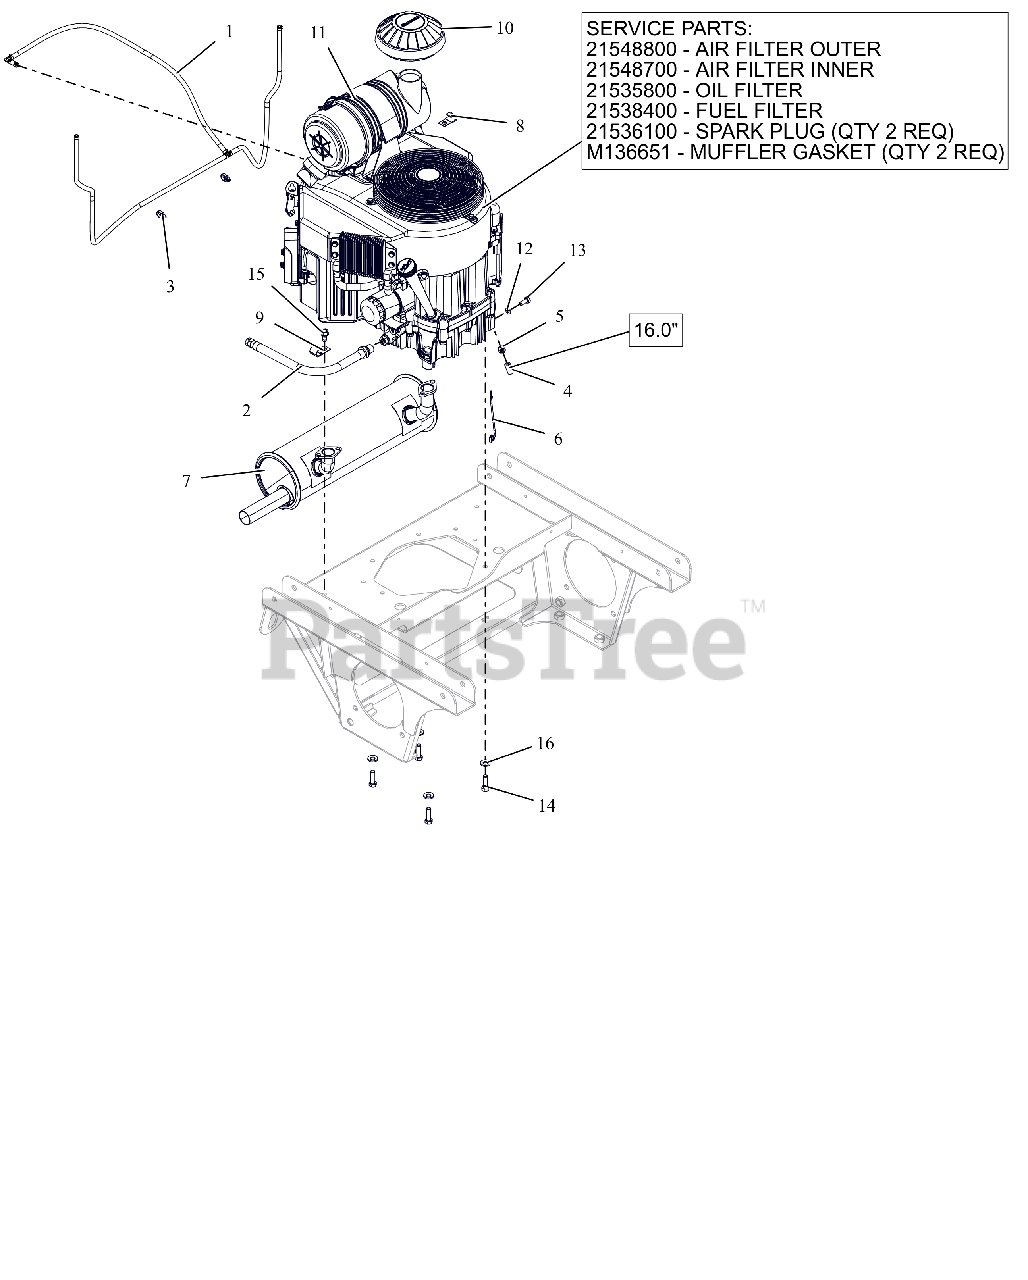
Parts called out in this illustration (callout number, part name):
1	ASM, VAPOR LINE
2	HOSE, OIL DRAIN
3	ROUTING CLIP (1/2" ID)
4	HOSE, .25 LOW-PERM BULK GAS
5	CLAMP, FUEL LINE
6	LEAD - STARTER SOLENOID
7	MUFFLER, 27-31 KAW
10	CAP, AIR CLEANER INTAKE (2")
11	ENGINE, KAWASAKI FX850
11	FILTER, OUTER
11	FILTER, INNER - KAW
11	FILTER,OIL - KAW
11	FUEL FILTER - KAWASAKI
11	PLUG, SPARK
11	GASKET, MUFFLER #
12	WSHR,LK-REG .312X.078 ZCC
13	BLT, HEX M8-1.25X20 G8.8 ZCC
14	BLT, HEX .38-16X1.25 G5 ZCC NT
15	SCR,TAP .375-16X.75 HWH TR ZCC
16	WASHER, 3/8" SPRING DISC
